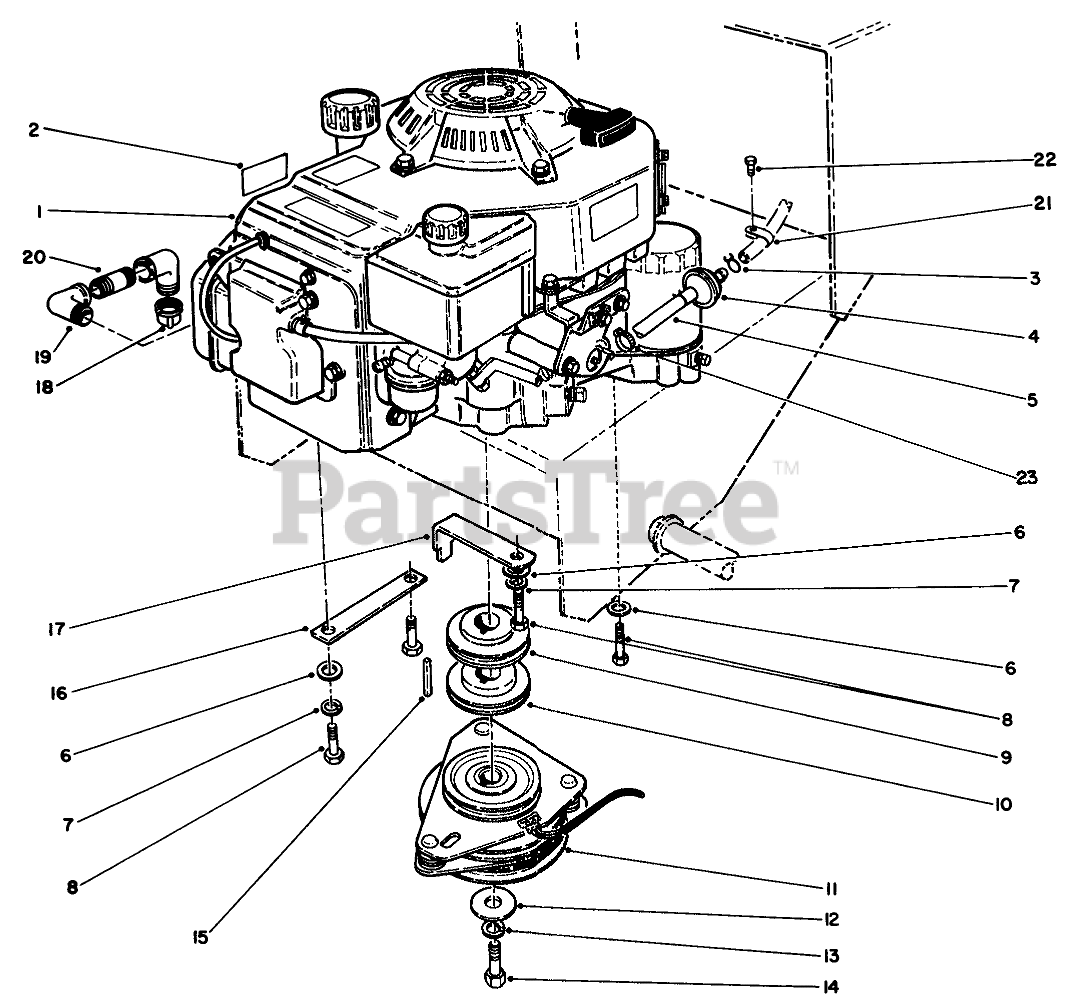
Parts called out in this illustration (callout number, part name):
2	DECAL-SURFACE, HOT
3	CLAMP-HOSE
4	FILTER-FUEL
5	HOSE-FUEL
6	WASHER-PLAIN
7	WASHER-LOCK
8	SCREW-HH
9	SHEAVE-UPPER HALF
10	SHEAVE-LOWER HALF
11	CLUTCH/BRAKE
12	WASHER-CLUTCH
13	WASHER-LOCK
14	SCREW-CLUTCH
15	KEY-SQUARE
16	Guard-Pulley
17	Retainer-Clutch
18	CAP-PIPE
19	ELBOW-STREET, 90 DEG
20	NIPPLE
21	CLAMP-CABLE
22	SCREW-HH
23	CLAMP-WORM
